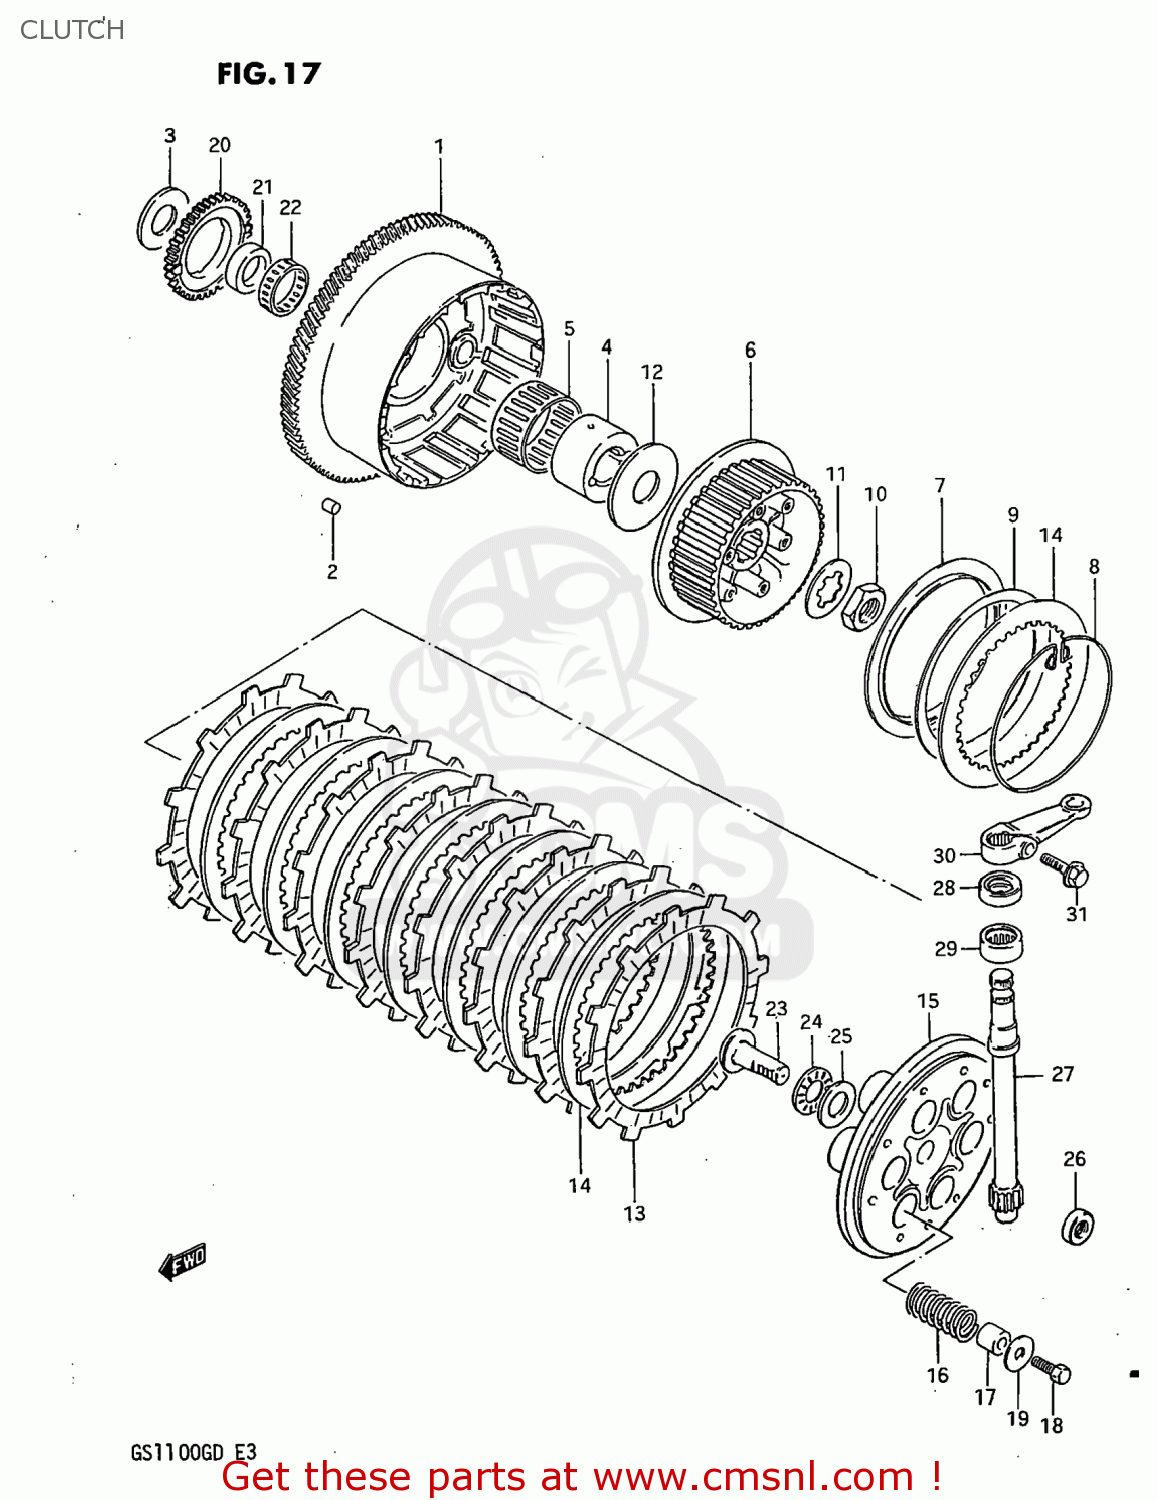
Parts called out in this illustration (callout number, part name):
1	GEAR ASSEMBLY,PRIMARY DRIVE
2	CUSHION,PRIMARY DRIVEN GEAR
3	WASHER
4	SPACER
5	BEARING
6	HUB,CLUTCH SLEEVE
7	SEAT,WAVE WASHER
8	RING,STOPPER
9	WASHER
10	NUT
11	WASHER,LOCK
12	WASHER(25X66X3.5)
13	PLATE,CLUTCH DRIVE (MCA)
14	PLATE,CLUTCH DRIVEN (NAS)
15	PLATE,CLUTCH PRESSURE
16	SPRING
17	SPACER
18	BOLT
19	WASHER
20	GEAR,ENG OIL PUMP DRIVE(NT:34)
21	SPACER,OIL PUMP DRIVE GEAR
22	BEARING(36X40X10)
23	RACK,CLUTCH RELEASE
24	BEARING(15X28X2)
25	WASHER
26	SEAL,OIL(10X16X5)
27	PINION,CLUTCH RELEASE
28	OIL SEAL
29	BEARING(15X22X12)
30	ARM,CLUTCH RELEASE
31	BOLT,REAR
